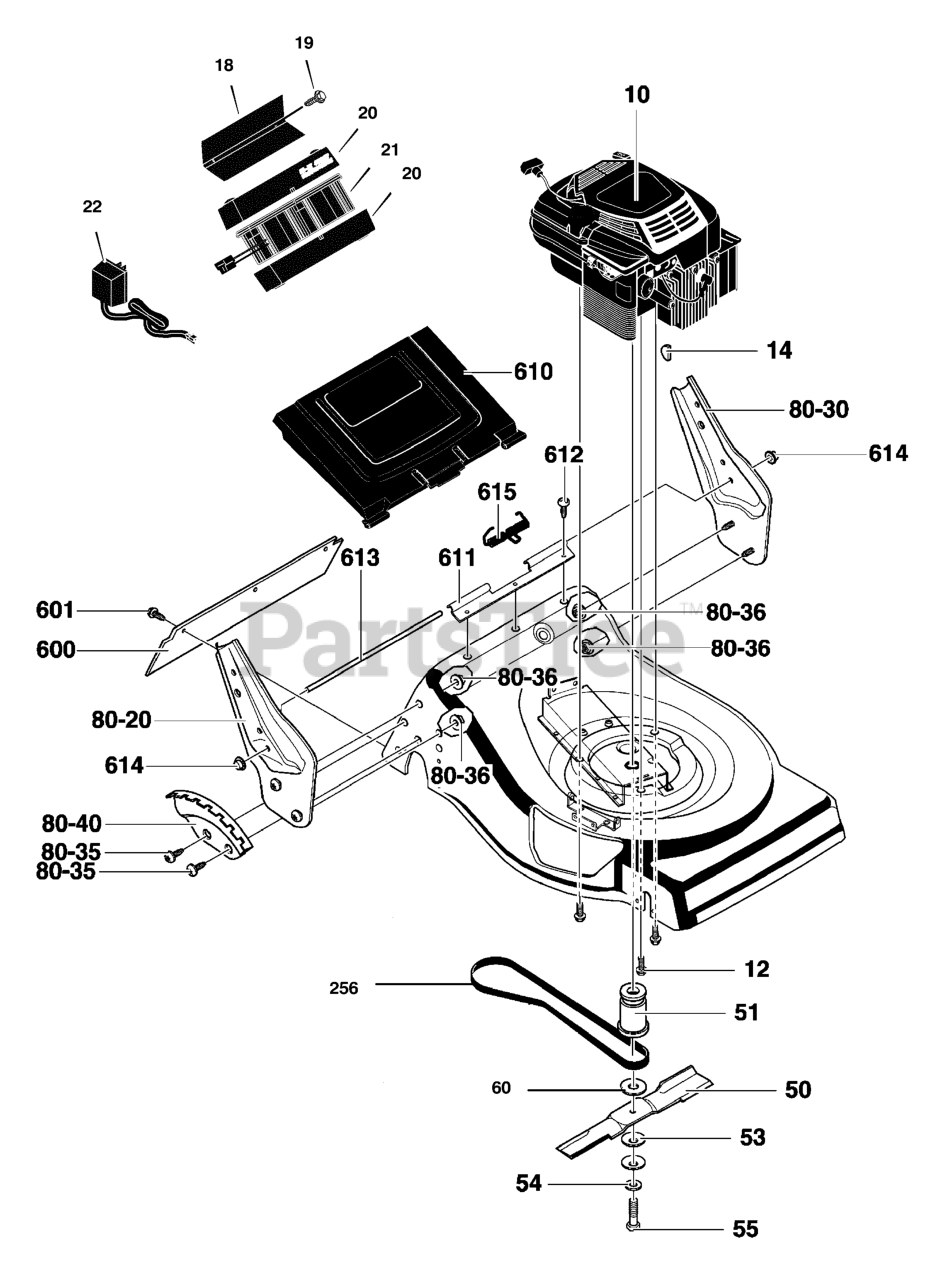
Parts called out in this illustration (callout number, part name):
10	Engine *
14	WOODRUFF KEY 505
18	BRACKET, BATTERY
19	SCREW *
20	CASE, BATTERY
21	BATTERY *
22	CHARGER, BATTERY
50	BLADE, 21" REVERSIBLE
51	ADAPTER, BLADE 21"
53	WASHER, BEVELLE
55	SCREW, 3/8-24 x 2.00
80-20	BRACKET, HANDLE RH
80-30	BRACKET, HANDLE LH
80-35	SCREW, 5/16-18 x 0.63
80-36	NUT, 5/16-16
80-40	INDEX, HEIGHT ADJ
256	BELT, V
600	DEFLECTOR, REAR
601	SCREW, 10-16X.50
610	DOOR, REAR 21
612	SCREW, 10-16X.50
613	ROD, PIVOT
614	CAP, PUSH ON
615	SPRING, TORSION
